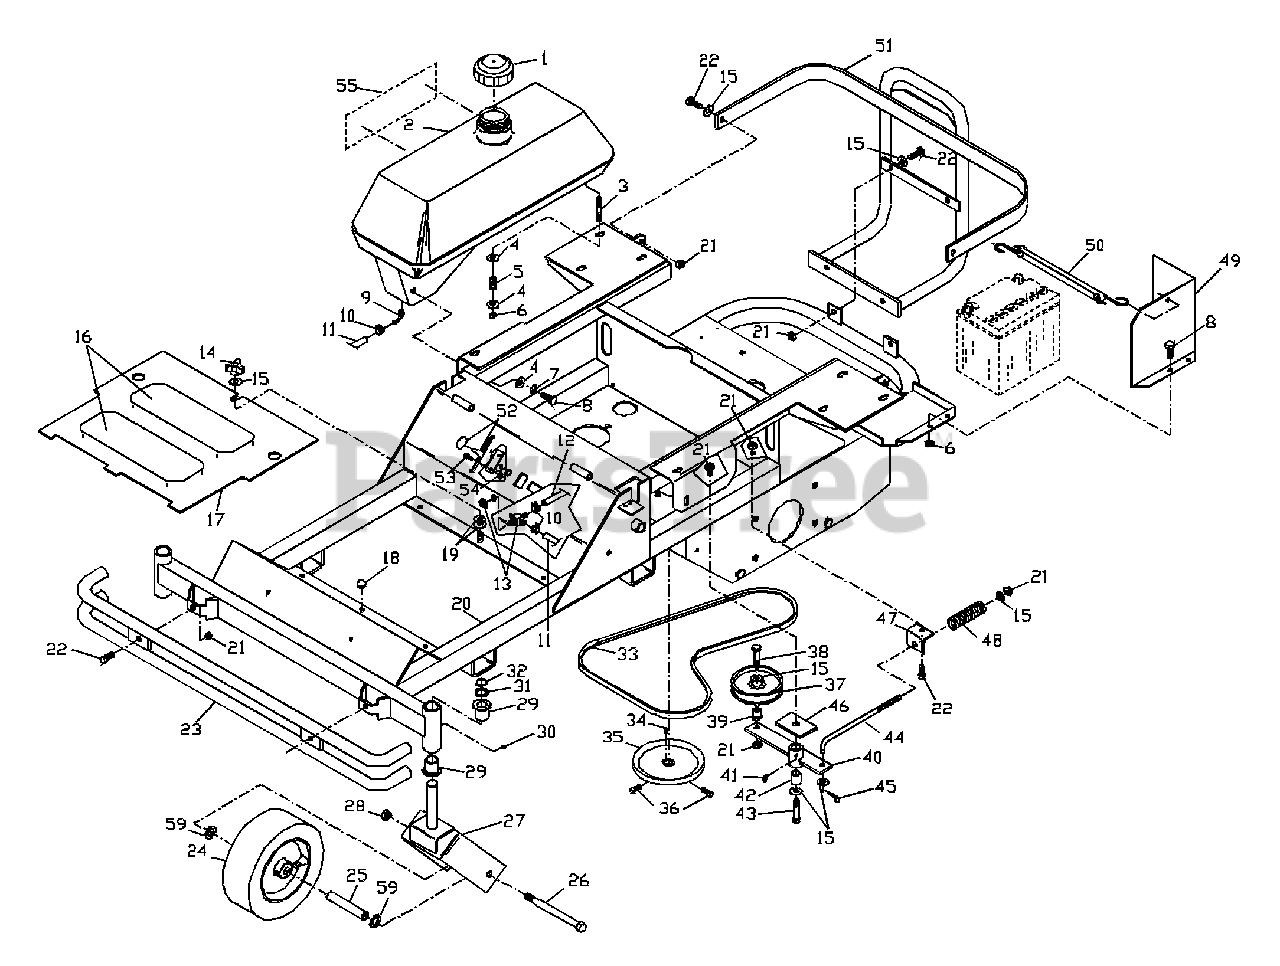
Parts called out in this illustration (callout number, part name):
1	FUEL CAP
2	FUEL TANK RT.
3	5/16C STUD
4	5/16 FLAT WASHER
6	NUT 5/16C CENTERLOCK
7	5/16 LOCKWASHER
8	HCS 5/16C X 3/4
9	90 DEG. HOSE BARB
10	HOSE CLAMP
11	FUEL LINE, TANK
12	FUEL LINE, ENGINE
13	FUEL VALVE
15	3/8 FLAT WASHER
16	ANTI-SKID PAD
17	FOOTPLATE
18	BUMPER, RUBBER
19	3/8 DISC WASHER
20	FRAME W/DECALS (KAW)
20	FRAME W/DECALS (KOHLER)
21	NUT 3/8C CENTERLOCK
22	HCS 3/8C X 1
23	BUMPER, FRONT
24	CASTER TIRE
24	ROLLER BEARING
24	ZERK
24	FLANGED BEARING
26	HCS 1/2C X 5 1/2
27	YOKE WELDMENT
28	NUT 1/2C NYLOC
29	FLANGE BUSHING
31	MACHINERY BUSHING
32	7/8" RETAINING RING
34	KEY 5 MM SQ. X 25 MM
36	5/16C X 5/8 SQ. HEAD
37	IDLER PULLEY
38	HCS 3/8C X 1 3/4
39	IDLER FLANGE BUSHING
40	IDLER ARM WELDMENT
41	45 DEG. ZERK
42	PIVOT BUSHING
43	HCS 3/8C X 3
44	TENSION ROD
45	COTTER PIN
46	SUPPORT PLATE
47	TENSION BRACKET
48	COMPRESSION SPRING
49	BATTERY GUARD W/DECALS
50	BATTERY STRAP
51	ENGINE GUARD W/DECALS
52	THROTTLE CABLE
53	#10-24 X 1/2 HCS
54	#10-24 NYLOC NUT
55	DECAL, ZTH4218
55	DECAL, ZTH4221
55	DECAL, ZTH4818
55	DECAL, ZTH4820
55	DECAL, ZTH4821
56	HCS 3/8C X 2 1/4 GD5
57	WEIGHT BLOCK
58	CHOKE CONTROL (KOHLER)
59	MACHINERY BUSHING
